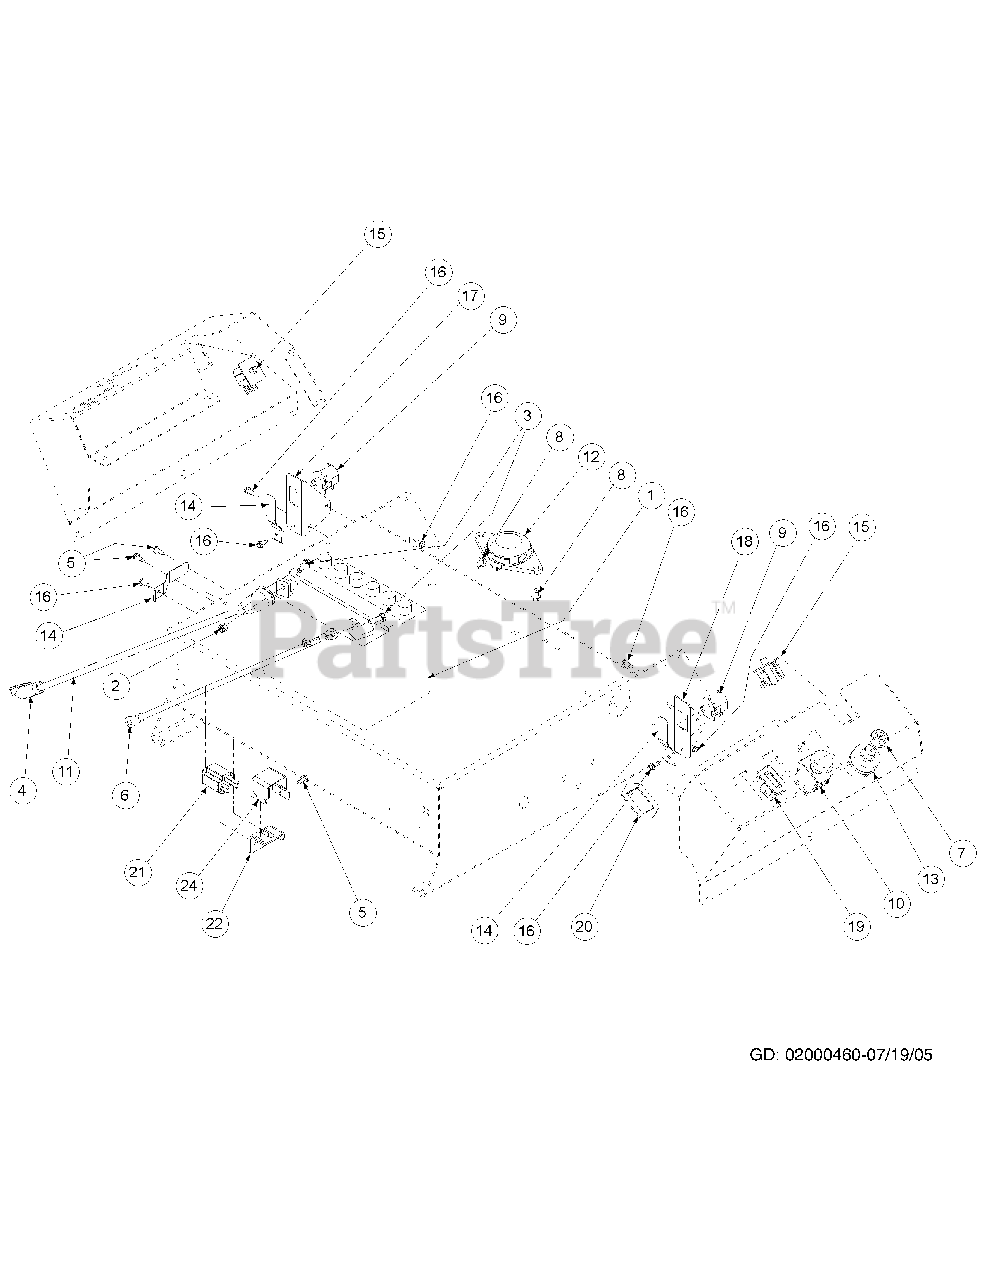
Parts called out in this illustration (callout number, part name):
1	Battery, 12V 225CCA 30Min
2	Lock Nut, Nylon Insert, 1/4-20
3	Hex Cap Screw, 1/4-20 x .75
4	Boot, 1" OD Rubber Battery-PST Red
5	Self Tapping Screw, 12-24
6	Cable, Battery, Black, 17"
7	Nut, 5/8-32, w/Cap
8	Self Tapping Screw, 1/4-20 x 1/2
9	Normally Closed Safety Switch
10	Electric PTO Switch
11	Cable, Battery, Red, 24"
12	Normally Closed Seat Switch
13	Switch, Ignition, 6 Pin
14	Safety Switch Retainer Spring
15	Neutral Switch
16	Self Tapping Screw, 10-32 x 1/2
17	Bracket, Safety Switch, Left Hand
18	Bracket, Safety Switch, Right Hand
19	Hour Meter
20	PTO Switch Bracket
21	Switch, Plunger
22	Control Housing Assembly
24	Switch, Clamp
